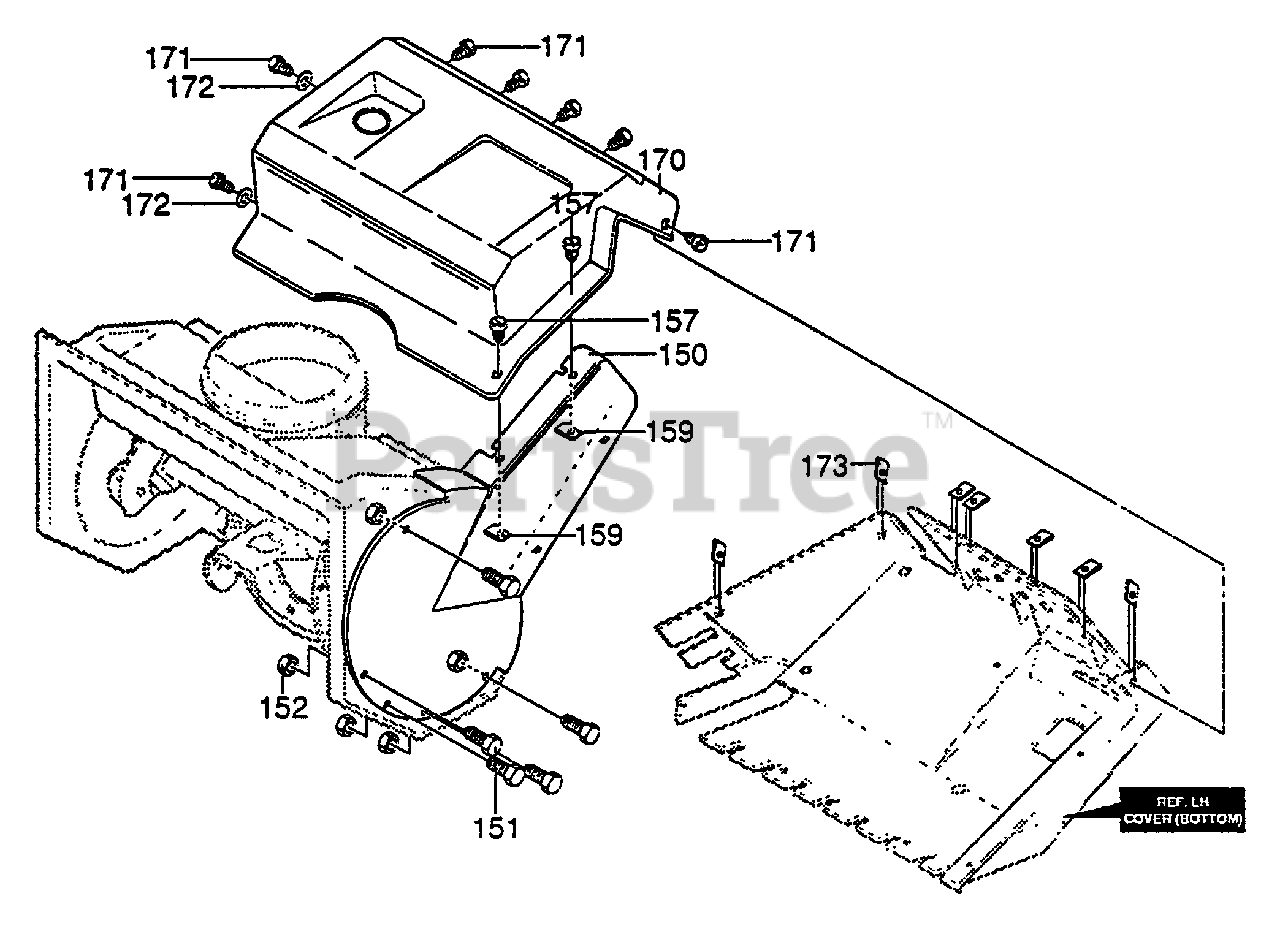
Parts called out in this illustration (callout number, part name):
150	COVER, BELT
151	SCREW, 10-24 X .50
152	NUT, #10-24
157	SCREW, 1/4-14 X .75
159	NUT, 1/4-10 SPEED J TYPE
170	COVER, TOP
171	SCREW, 1/4-14 X .75
172	FLATWASHER .281 X .63 X .065
173	NUT, 1/4-10 SPEED J TYPE
